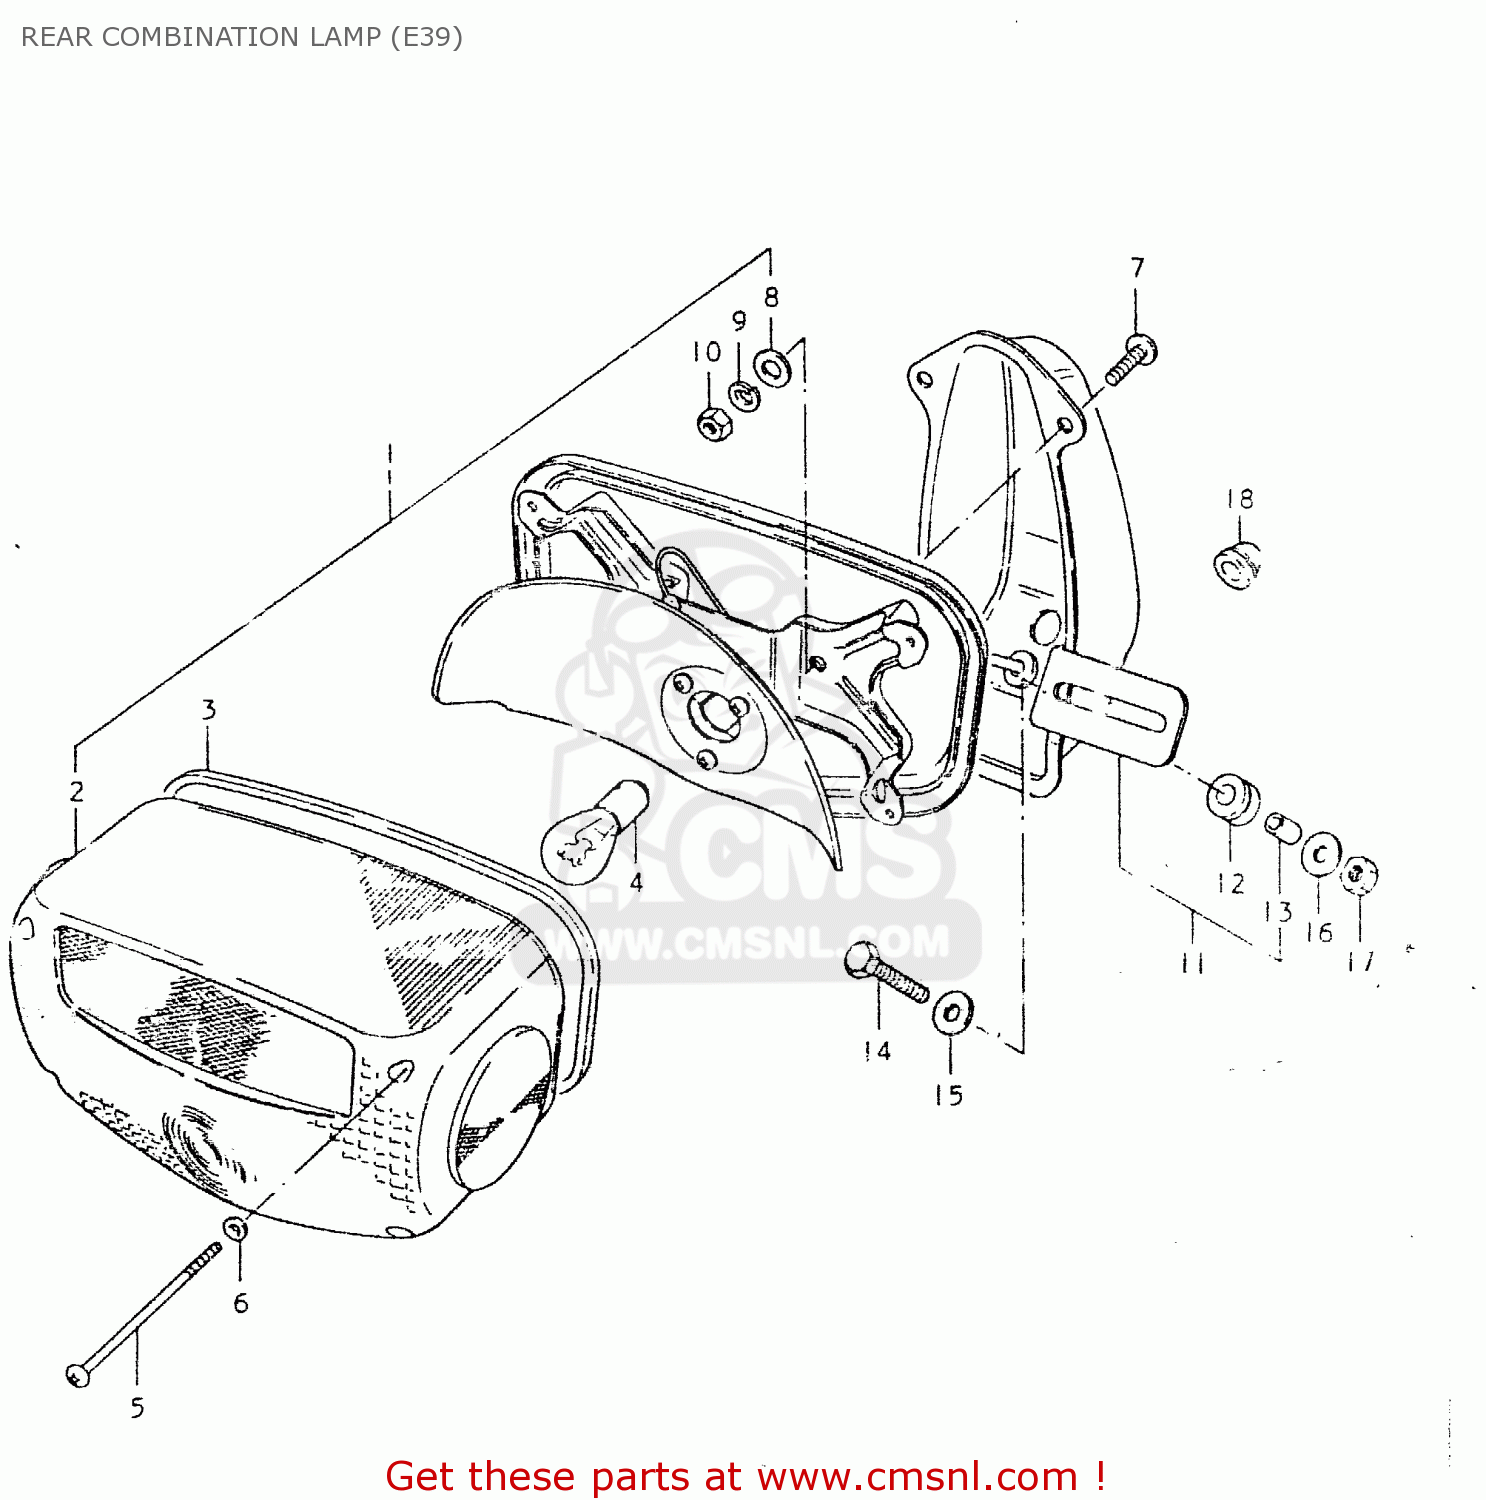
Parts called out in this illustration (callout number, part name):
1	LAMP UNIT, TAIL
2	LENS,REAR COMBINATION LAMP
3	GASKET (NAS)
4	BULB 12V21/5W
5	SCREW (4X55)
6	GASKET (NAS)
7	SCREW 6X12
8	WASHER
9	LOCK WASHER
10	NUT
11	BRACKET ASSY
12	CUSHION
13	SPACER,REAR COMBINATION LAMP
14	BOLT
15	WASHER (6.5X20X1.2)
16	WASHER
17	NUT
18	GROMMET
